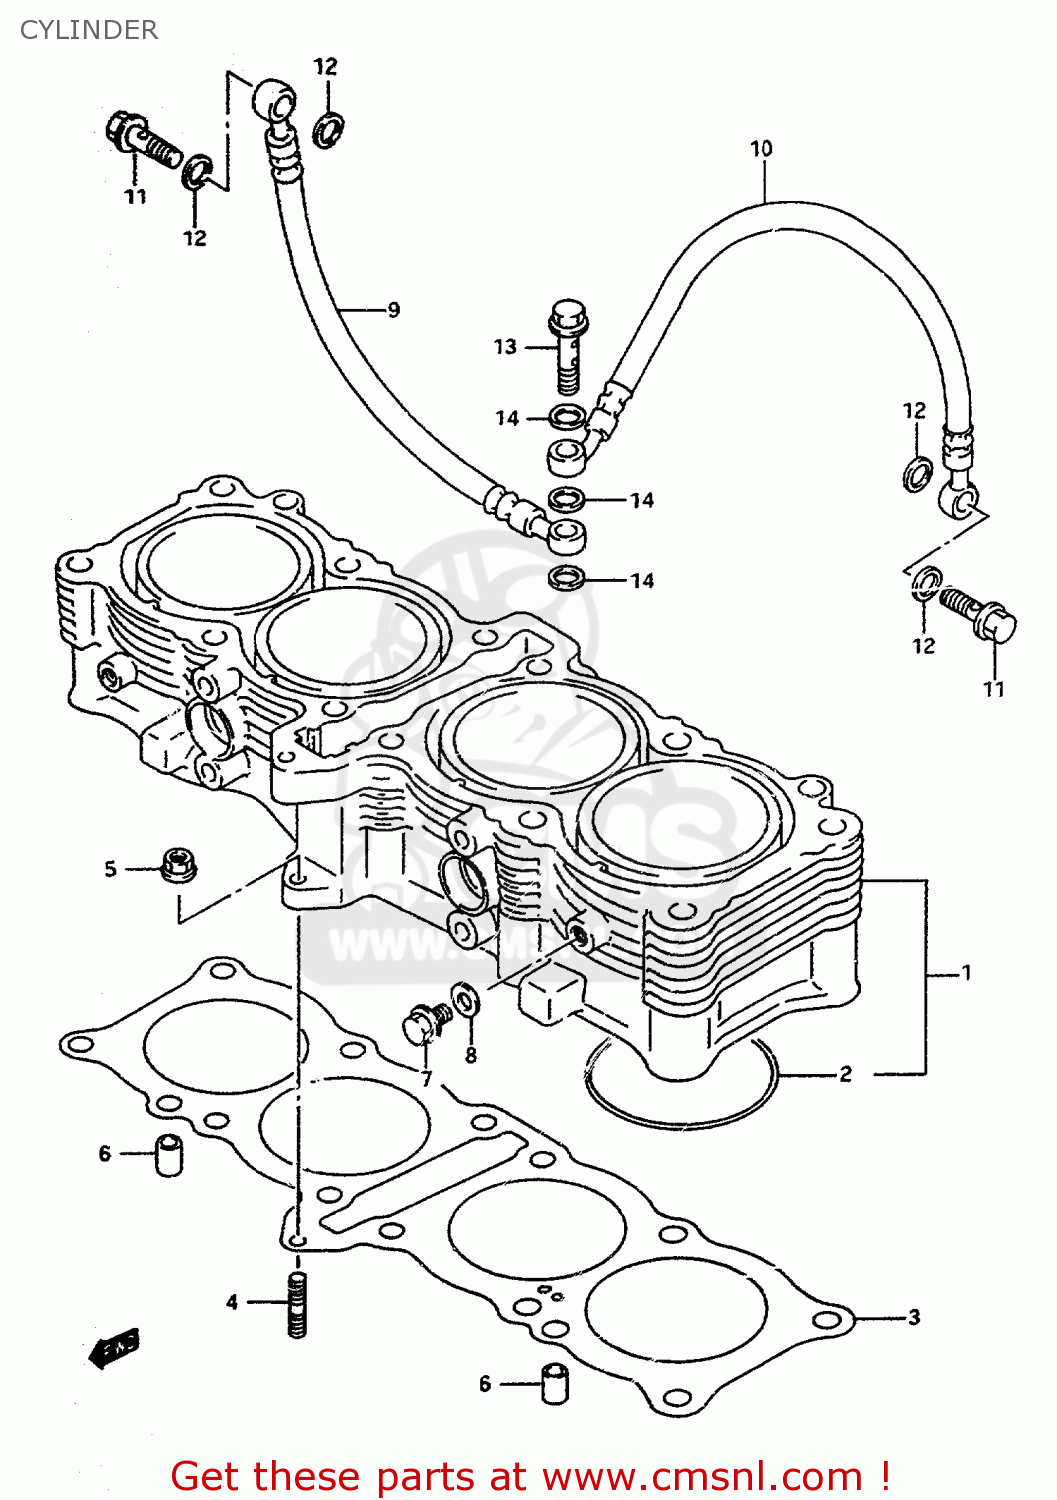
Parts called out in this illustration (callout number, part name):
1	CYLINDER
2	O RING(D:2.6,ID:69.6)
3	GASKET,CYLINDER
4	STUD,M6X1X32
5	NUT
6	PIN
7	BOLT,DRAIN
8	GASKET 8.2X14X1 (NAS)
9	HOSE,CYLINDER HEAD OIL,R
10	HOSE,CYLINDER HEAD OIL,L
11	BOLT,OIL PIPE UNION,NO
12	GASKET(8.2X14X1) (NAS)
13	BOLT,OIL PIPE UNION,NO
14	WASHER(10X15X1.5)
